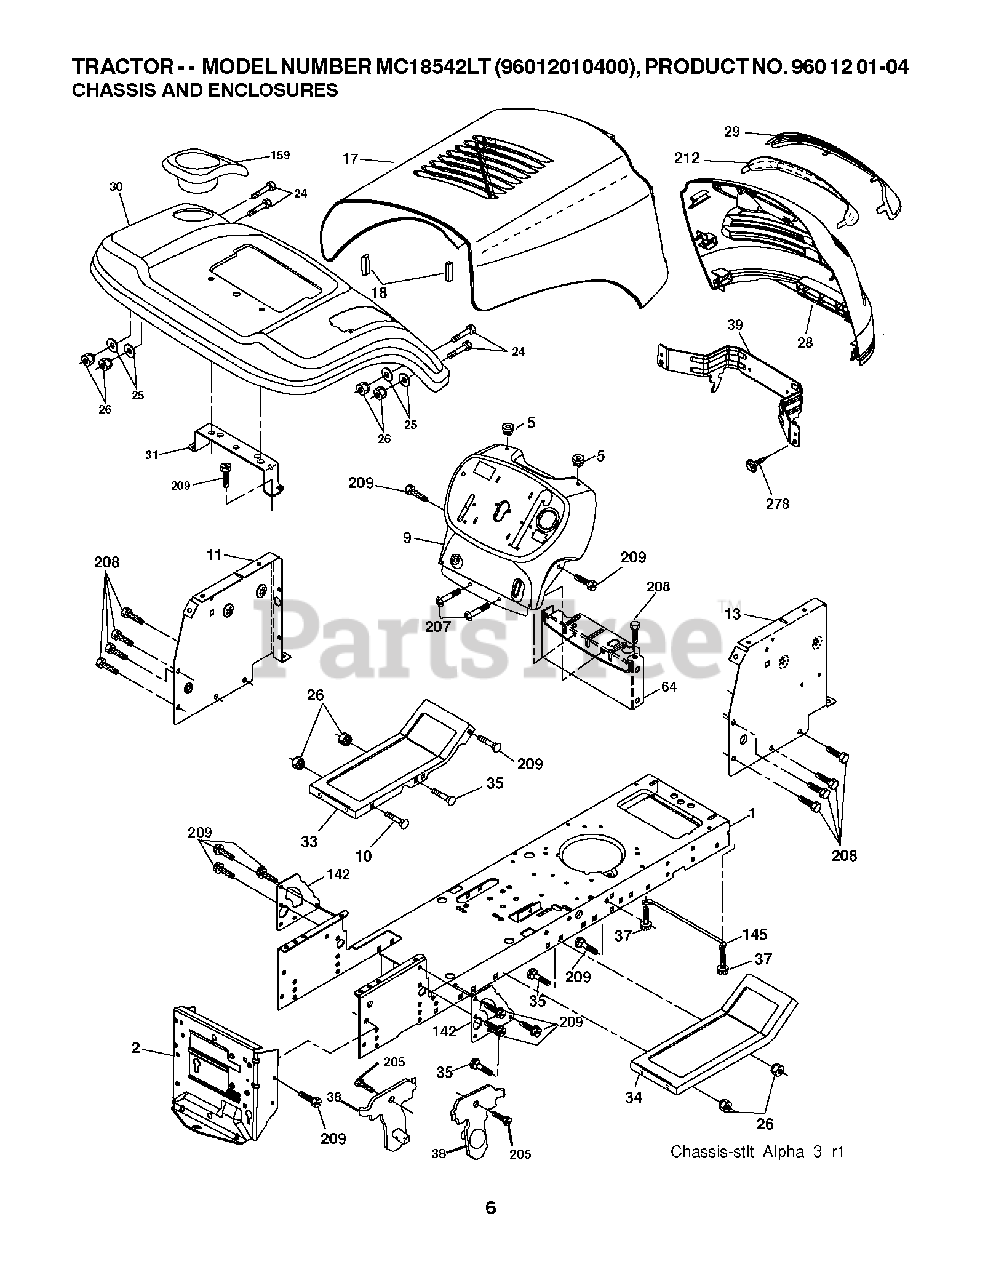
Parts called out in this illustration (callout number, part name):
1	CHASSIS STAMPING
2	DRAWBAR, 12GA
5	BUMPER.RUBBER.HOOD
11	PANEL.DASH.LH.LTX
17	GRILLE.ALPHA.LT.NO LIGHTS
18	BUMPER.HOOD.LARGE.1.75"
25	WASHER
26	NUT
28	GRILLE.ASM.ALPHA
29	LENS.ALPHA.BAR.LT
30	FENDER.PNT.LTST.W/SHFT.WCUP
31	BRACKET FENDER
33	FOOTREST.PNT.RH
37	SCREW LT
38	BRACKET.ASM.PIVOT.MOWER.REAR
39	BRACKET.PIVOT.ALPHA.LT
64	DASH LOWER
142	PLATE REINFORCEMENT
145	ROD.PIVOT.HOOD
159	CUPHOLDER.BLACK
205	SCREW LT
207	SCREW, 5/16-18 X 1/2
208	SCREW 3/8-16X1/2
209	SCREW, 3/8-16X3/4
212	INSERT.ALPHA.REFLECTIVE.LT.
278	SCREW.#10 X 0.750.BOS (2 2)
